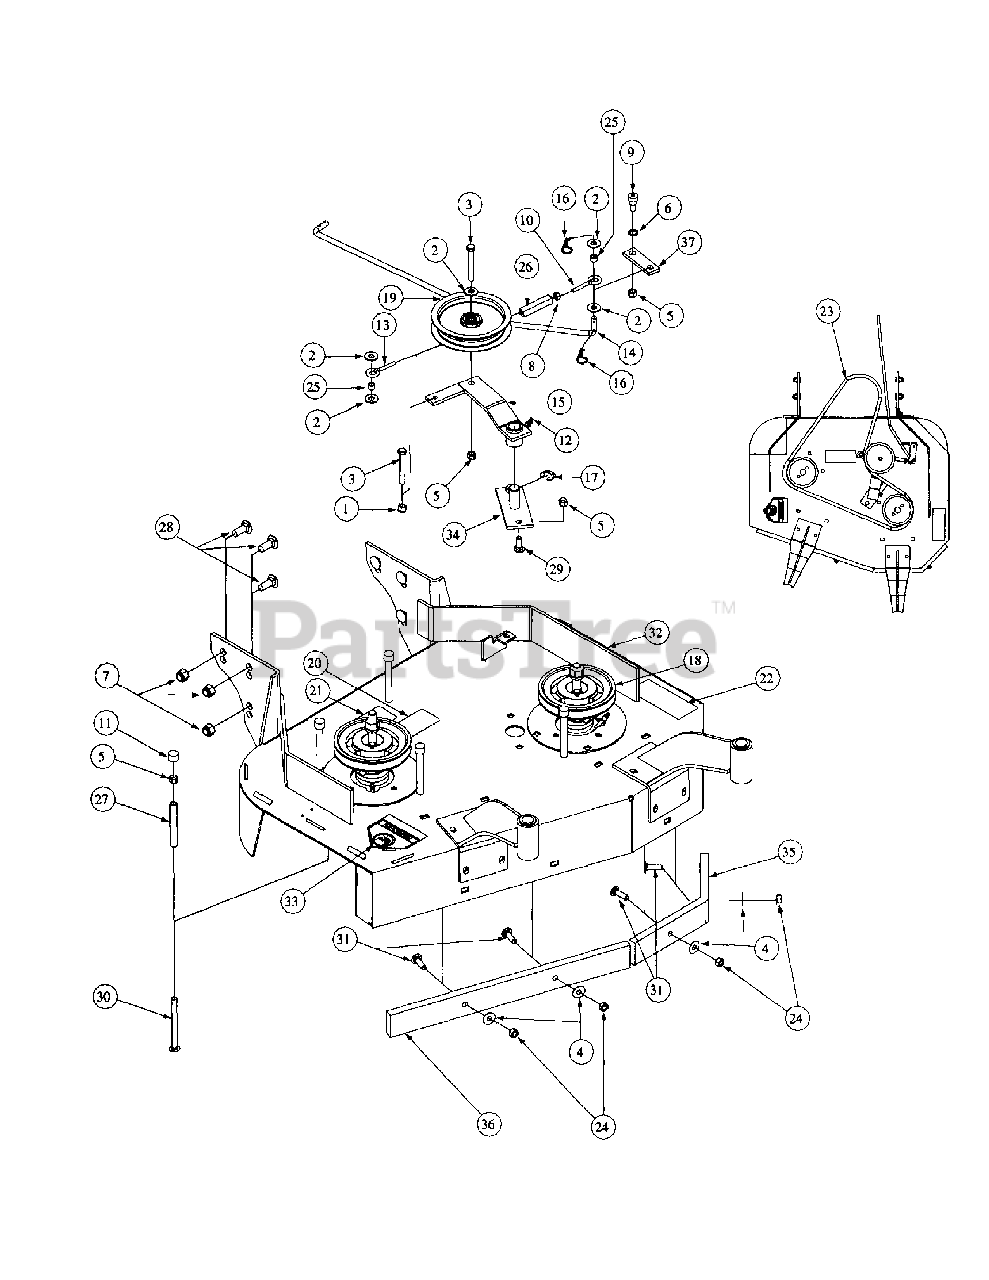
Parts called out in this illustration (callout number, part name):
1	Hex Nut, 3/8-16
2	Flat Washer, 3/8 Zinc
3	Hex Cap Screw, 3/8-16, 1
4	Flat Washer, 3/8 Zinc
5	Lock Nut, Nylon Insert, 3/8-16
6	Shim Washer
7	Lock Nut, Nylon Insert, 1/2-13
8	Hex Nut, 5/16-18
9	Shoulder Bolt
10	Eye Bolt, Right Hand
11	Cap, Black Vinyl
12	Grease Fitting, 1/4-28 x 3/16
13	Eye Bolt, Left Hand
14	Blade Clutch, Rod
15	Idler Arm
16	Hair Pin, 3/8"-1/2"
17	E-Ring, Retainer
18	Pulley Deck
19	Idler Deck Take-up
20	Decal Rotating Blade
21	Decal Warning Safety
22	Decal, Warning Shield
23	Belt Drive
24	Lock Nut, 3/8-16
25	Turnbuckle, Sleeve
26	Turnbuckle
27	Spacer, Belt Guide
28	Carriage Bolt, 1/2-13 x 1-1/4
29	Carriage Bolt, 3/8-16 x 2
30	Carriage Bolt, 3/8-16 x 4.5
31	Carriage Screw, 3/8-16 x 1.25
32	Deck 32"
33	Decal, Danger, Hands and Feet
34	Idler Base
35	Bumper, Deck 32"
36	Bumper, Deck 32"
37	Pivot Arm
